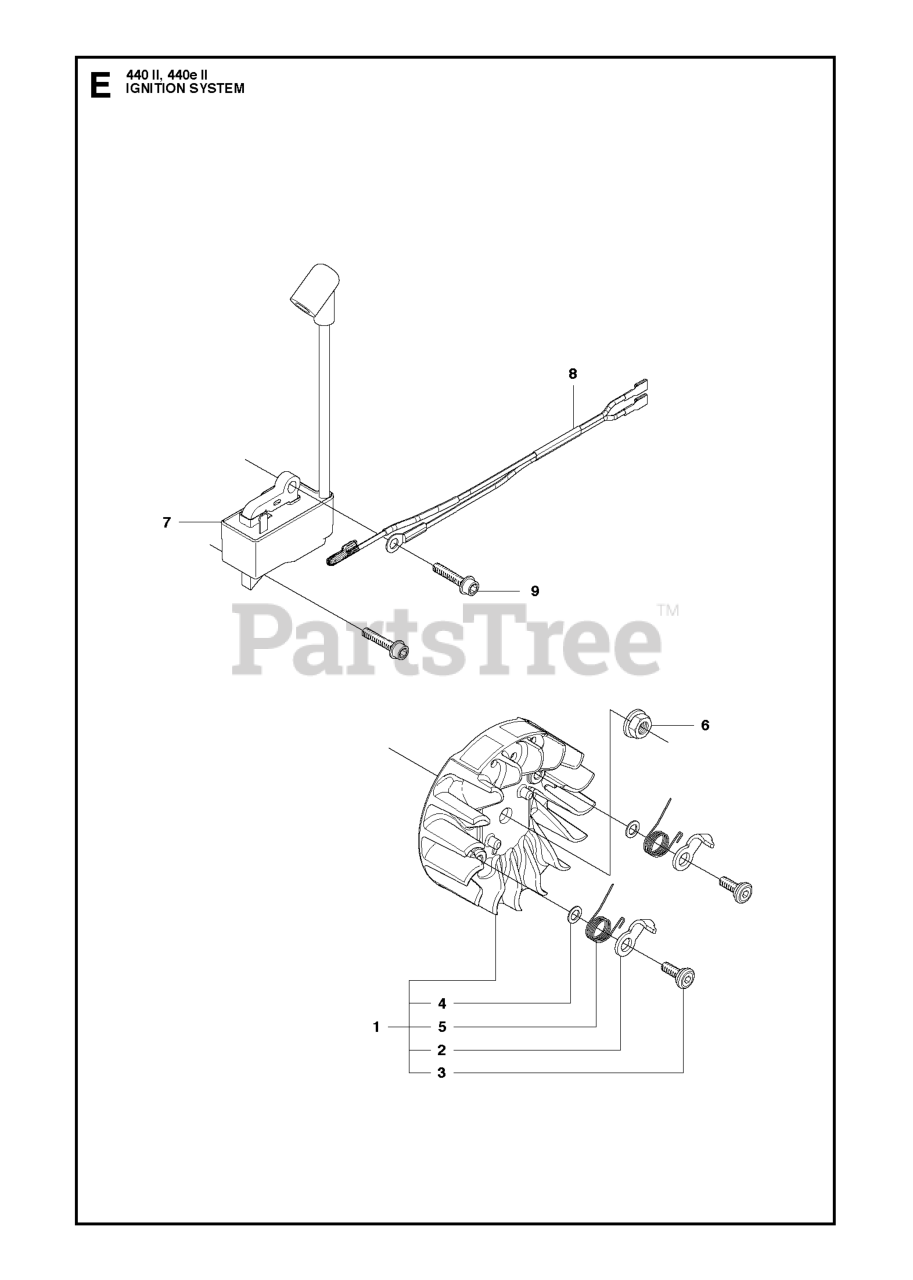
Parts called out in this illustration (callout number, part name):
1	FLYWHEEL ASSY D90
6	NUT W/ WASHER
7	IGNITION MODULE
8	WIRING ASSY
